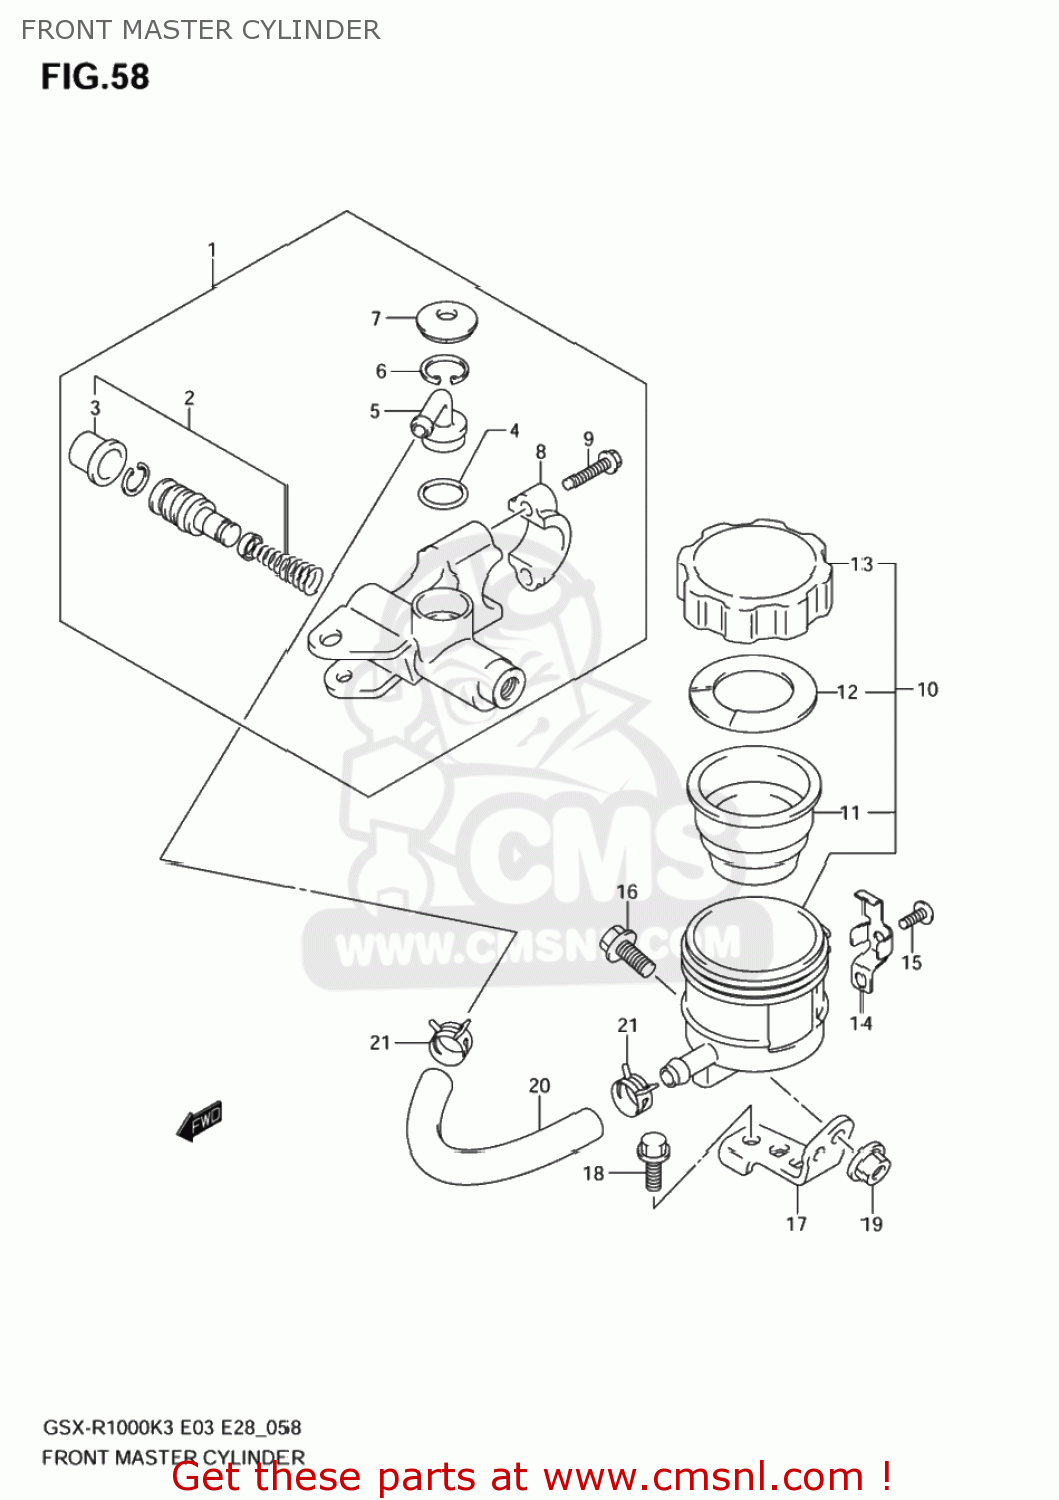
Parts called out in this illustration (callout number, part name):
1	CYLINDER ASSY,FR MASTER
2	PISTON & CUP SET
3	BOOT
4	O RING
5	CONNECTOR
6	CIRCLIP
7	COVER,DUST
8	HOLDER
9	BOLT(6X22)
10	TANK ASSY,RESERVOIR
11	DIAPHRAGM
12	PLATE,DIAPHRAGM
13	CAP
14	PLATE,RESERVOIR TANK CAP
15	SCREW
16	BOLT
17	BRACKET,RESERVOIR TANK
18	BOLT
19	NUT
20	HOSE,FR RESERVOIR TANK
21	CLAMP,RESERVOIR TANK FR
